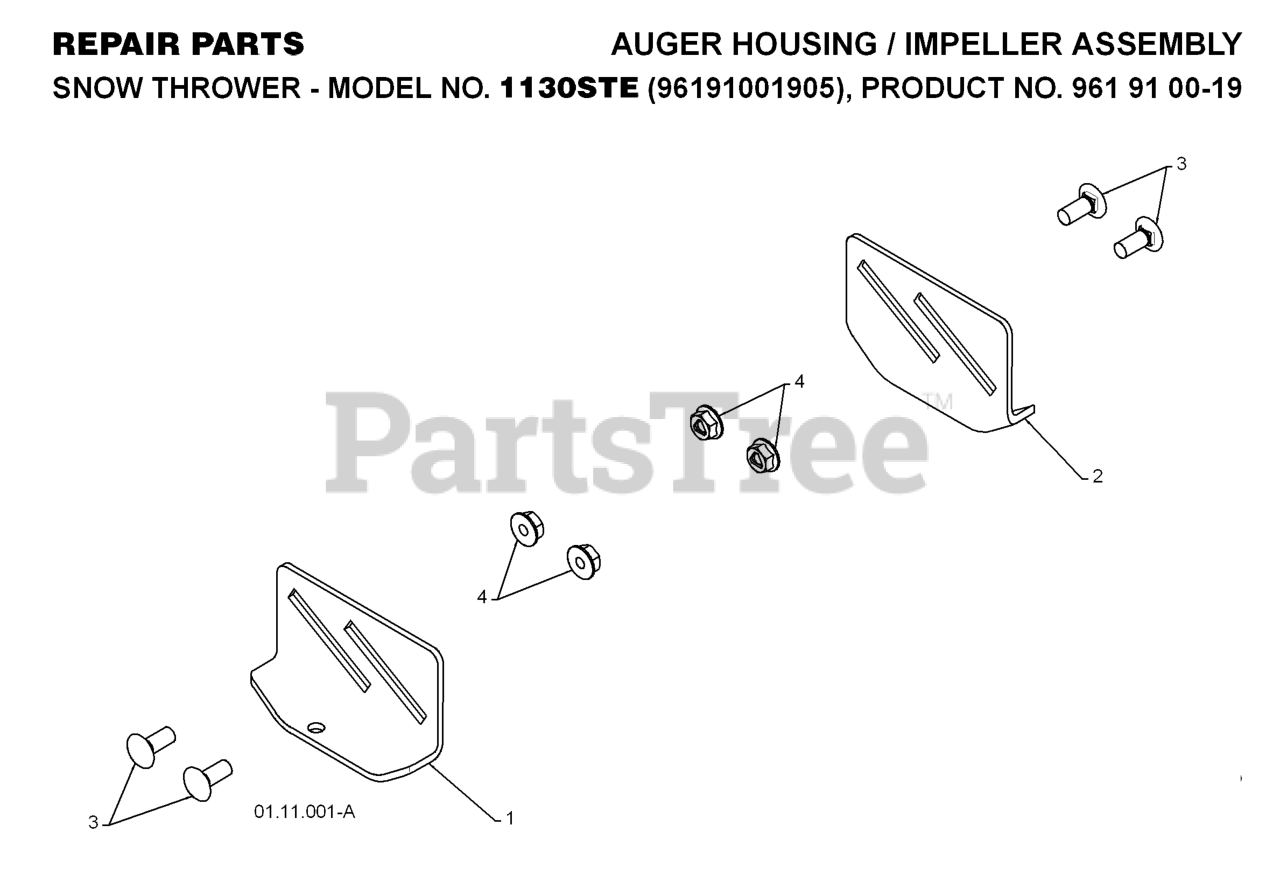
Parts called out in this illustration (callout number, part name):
1	SKID PLATE LH
2	SKID PLATE RH
3	BOLT
4	NUT.LOCK.5/16-18
